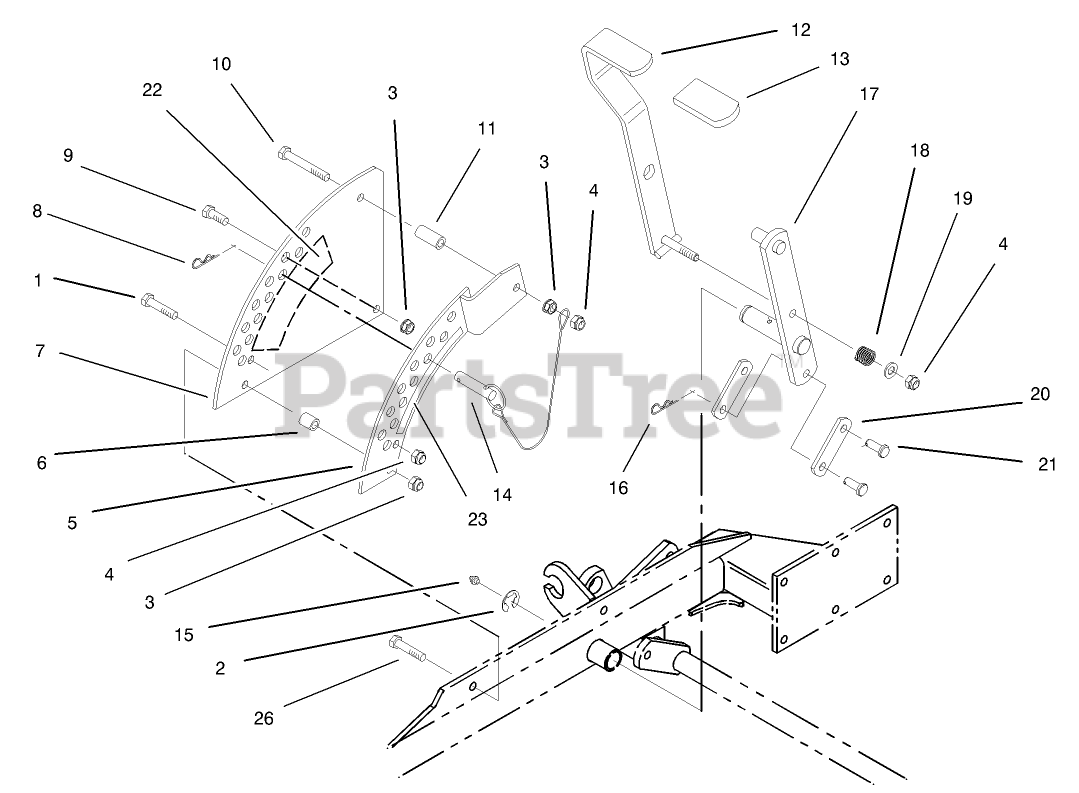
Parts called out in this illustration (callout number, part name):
1	SCREW-HH
2	RING-RETAINING, EXT
3	NUT-HHF, WHIZ
4	NUT-LOCK, NI
5	PLATE-LIFT, DECK
6	BUSHING-LEVER, LIFT
7	PLATE-LIFT, DECK
8	PIN-COTTER
9	SCREW-HH
10	SCREW-HH
11	BUSHING-LEVER, LIFT
12	HANDLE-LIFT
13	GRIP-LEVER, LIFT
14	PIN-HITCH (W/LANYARD)
15	FITTING-GREASE
16	PIN-COTTER
17	ARM-LIFT
18	SPRING-COMPRESSION
19	WASHER-FLAT
20	ARM-LIFT, DECK
21	PIN-CLEVIS
22	DECAL-DECK HEIGHT, OUTER
23	DECAL-DECK HEIGHT, INNER
26	SCREW-HH
